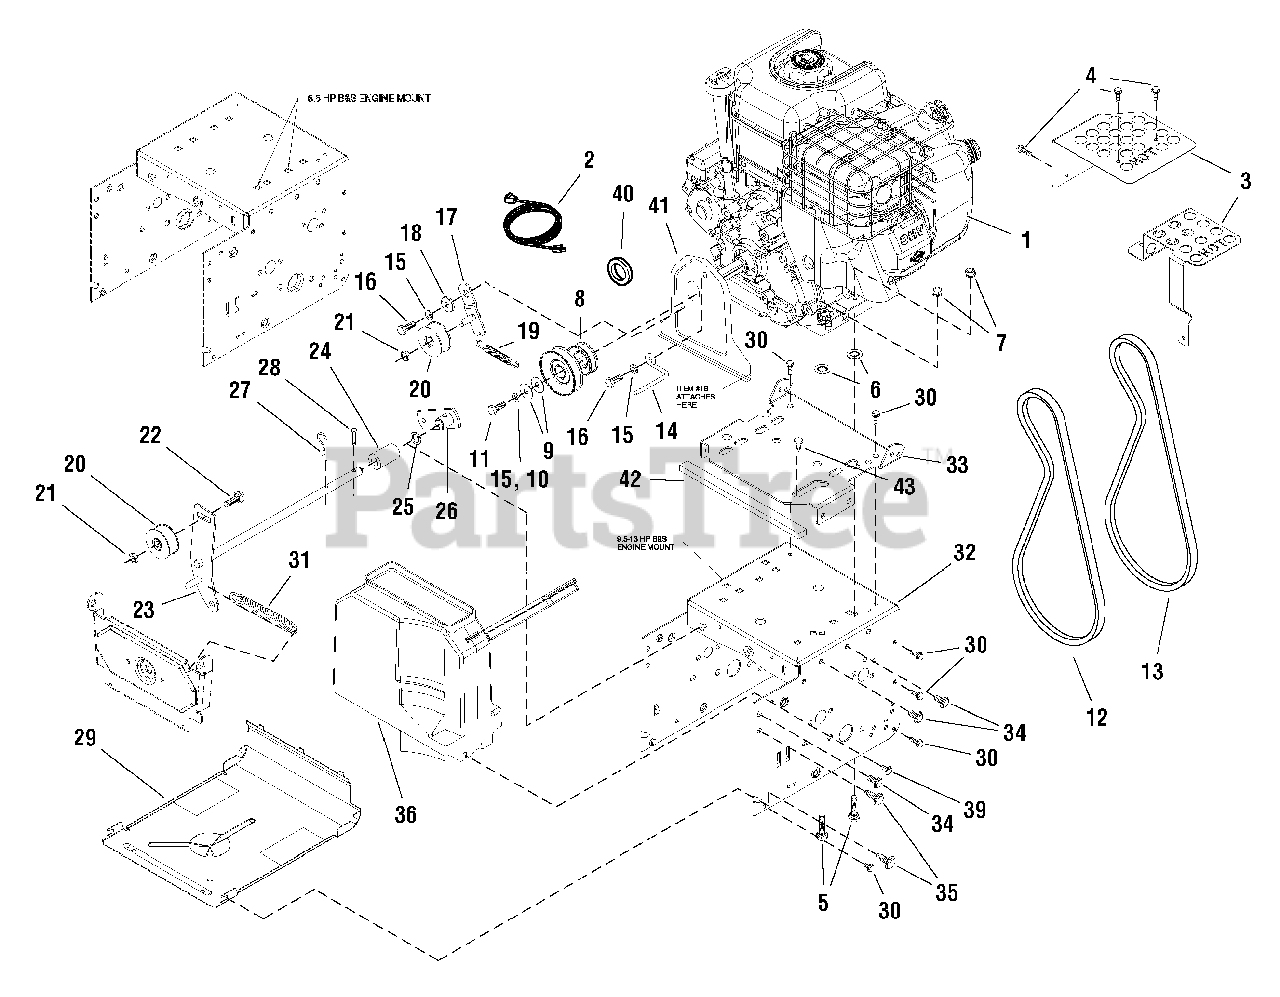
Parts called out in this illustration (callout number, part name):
2	CORD, Electric Start
3	GUARD, Muffler
4	SCREW, Hex Washer Head Taptite #10C x 1/2
5	CARRIAGE BOLT, 5/16-18 x 1-1/2
7	NUT, Hex Flange 5/16-18 Whiz Lock
7	NUT, Hex Flange 5/16-18 ESNA
8	PULLEY, Engine
9	WASHER, 5/16-1
9	WASHER, 3/8
10	LOCKWASHER, Spring 3/8
11	CAPSCREW, Hex Head 5/16-24 x 1-1/4 G8
11	CAPSCREW, Hex Head 3/8-24 x 1-1/4 G8
12	V-BELT, 3L 33.13 Drive
13	V-BELT, 4L 36.5 Auger
13	V-BELT, 4L 38.5 Auger
14	STOP, Belt
15	LOCKWASHER, Spring 5/16
16	CAPSCREW, Hex Head 5/16-24 x 3/4 G5
17	IDLER BRACKET ASSEMBLY, Drive Belt
18	BUSHING, Idler Bracket
19	SPRING, Extension Idler
20	IDLER, Plastic Ball Bearing
21	NUT, Hex Centerlock Jam 3/8-16
22	CARRIAGE, 3/8-16 x 1-1/4
23	IDLER ASSEMBLY, Auger
24	SPACER/AUGER BRACKET
25	WASHER, 1/2
26	BRACKET & HUB ASSEMBLY, Spring Attached
27	PIN, Hair
28	PIN, Clevis
29	PANEL, Bottom
30	SCREW, Hex Washer Head Taptite 1/4-20 x 5/8
31	SPRING, Extension Auger Idler
32	FRAME, Standard Turn Axle
32	FRAME, EZ Turn Axle
33	ENGINE MOUNT
34	SCREW, Hex Washer Head Taptite 5/16-18 x 1/2
35	SCREW, Hex Washer Head Taptite 5/16-18 x 3/4
36	COVER, Belt w/Toolbox
39	SCREW, 1/4-AB x 3/4 Hex
40	SHAFT, Seal
41	SEAL, Plate
42	SEAL, Strip
43	CLIP, Pine Tree
